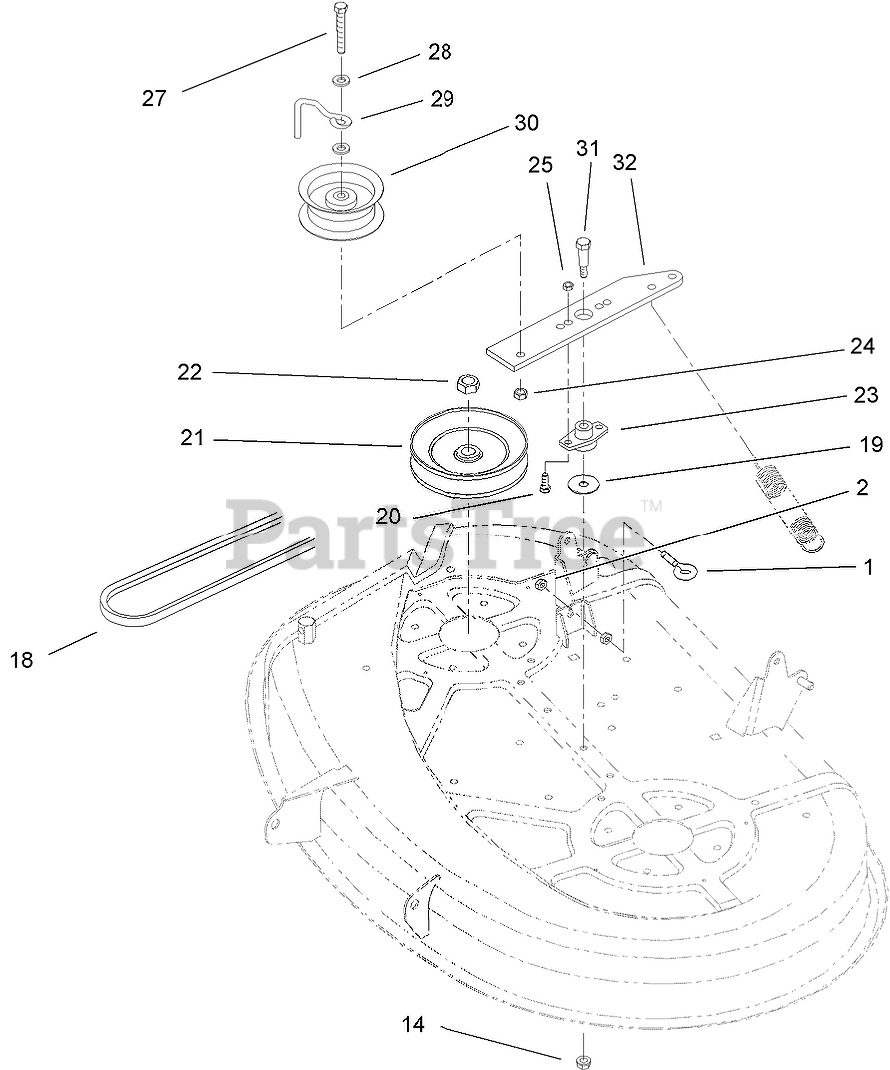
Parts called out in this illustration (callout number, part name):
1	EYEBOLT
2	NUT-JAM
14	NUT-LOCK, NI
18	BELT-V
19	WASHER-FLAT
20	SCREW-HH
21	PULLEY
22	NUT-HEX
23	BUSHING-ARM, IDLER
24	NUT-LOCK, NI
25	NUT-LOCK, NI
27	SCREW-HH
28	WASHER-FLAT
29	GUIDE-IDLER, BELT
30	PULLEY-IDLER, FLAT
31	SCREW-SHOULDER, HH
32	ARM-IDLER
